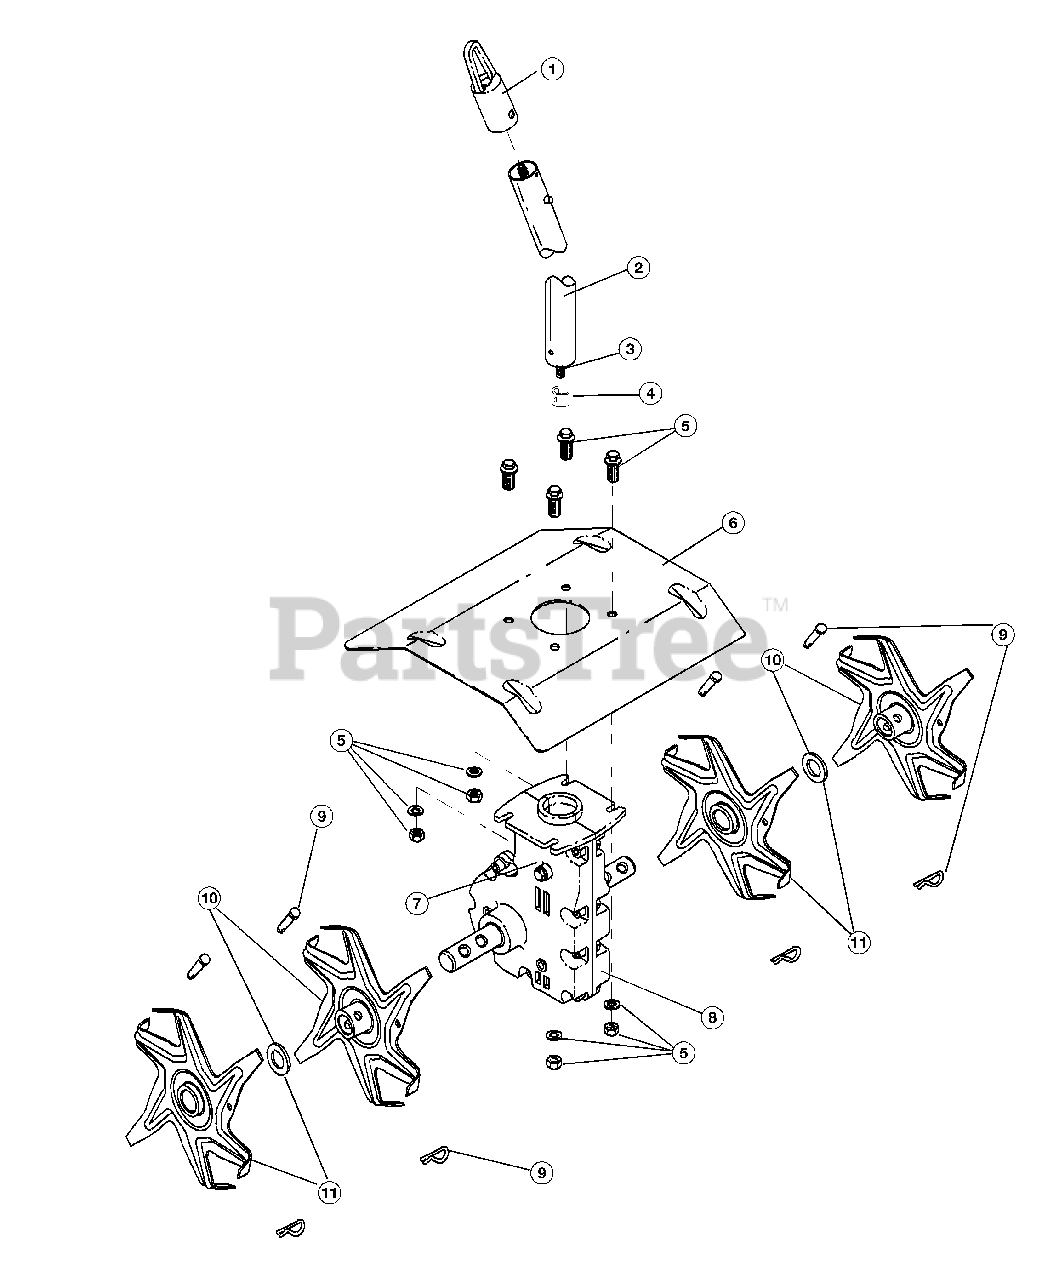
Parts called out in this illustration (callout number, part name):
1	Accessory Hanger
2	Drive Shaft Housing Assembly
3	Flexible Drive Shaft
4	Retainer Sleeve
5	Guard Mounting Hardware Set
6	Guard
7	Bolt
8	Gear Box Assembly
9	Tine Fastener Assembly
10	Tine Assembly (Left Outer or Right Inner)
11	Tine Assembly (Left Inner or Right Outer)
